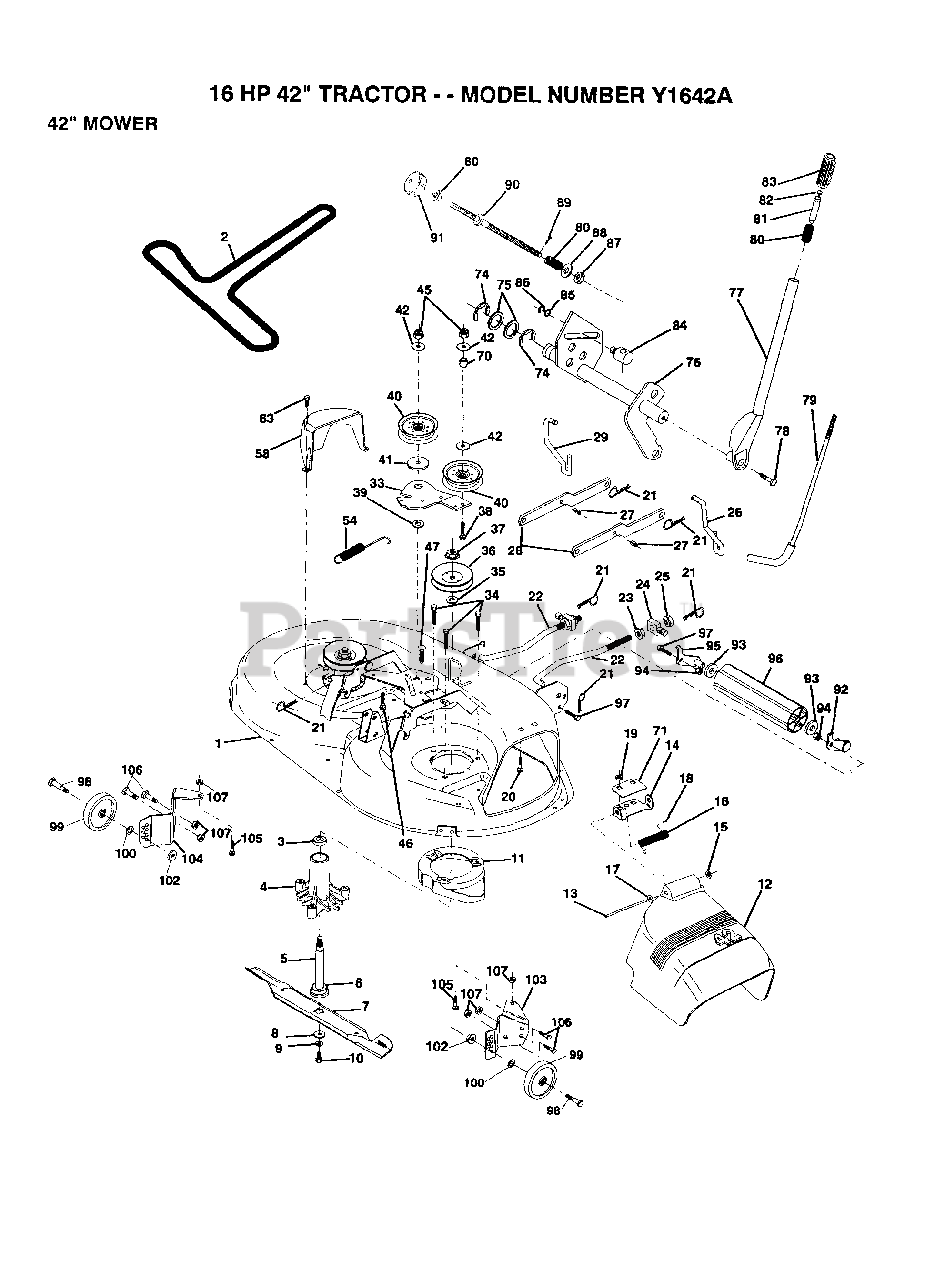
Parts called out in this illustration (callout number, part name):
2	BELT-V.92.4.MWR
3	BEARING
4	HSG ASM MANDREL
6	BEARING.BALL
8	WASHER BLADE
10	BLADE BOLT
12	DEFLECTOR.SHIELD
13	HINGE ROD
14	DEFLECTOR BRKT
15	NUT PUSH M
16	SPRING TORSION
17	WASHER
18	CAP-SLEEVE LT
20	BOLT
22	LINK.FRONT
23	NUT
24	TRUNION
25	NUT.LK.W/WSH.1/2.
26	LIFT LINK RH
27	"PIN,SPRING"
29	LINK LIFT LH
33	IDLER ARM
35	WASHER
38	BOLT
39	HARDENED WASHER
40	FLAT IDLER PULLEY
41	SPACER RETAINER
42	WASHER
46	BOLT
47	XMAS TREE FASTNER
54	SPRING.EXTENSION
60	NUT
63	SCREW LT
71	STIFFENER BRKT
74	E-RING
75	WASHER
78	"BOLT,HEX"
79	LEVER ROD LT
80	SPRING T
83	GRIP
84	TRUNION LT
85	WASHER
86	KLIP RING
87	NUT T
88	WASHER
90	ROD LIFT LT
93	WASHER
97	BOLT
98	BOLT M
99	WHEEL.GAGE.BLK.PL
100	WASHER
102	NUT
106	BOLT
